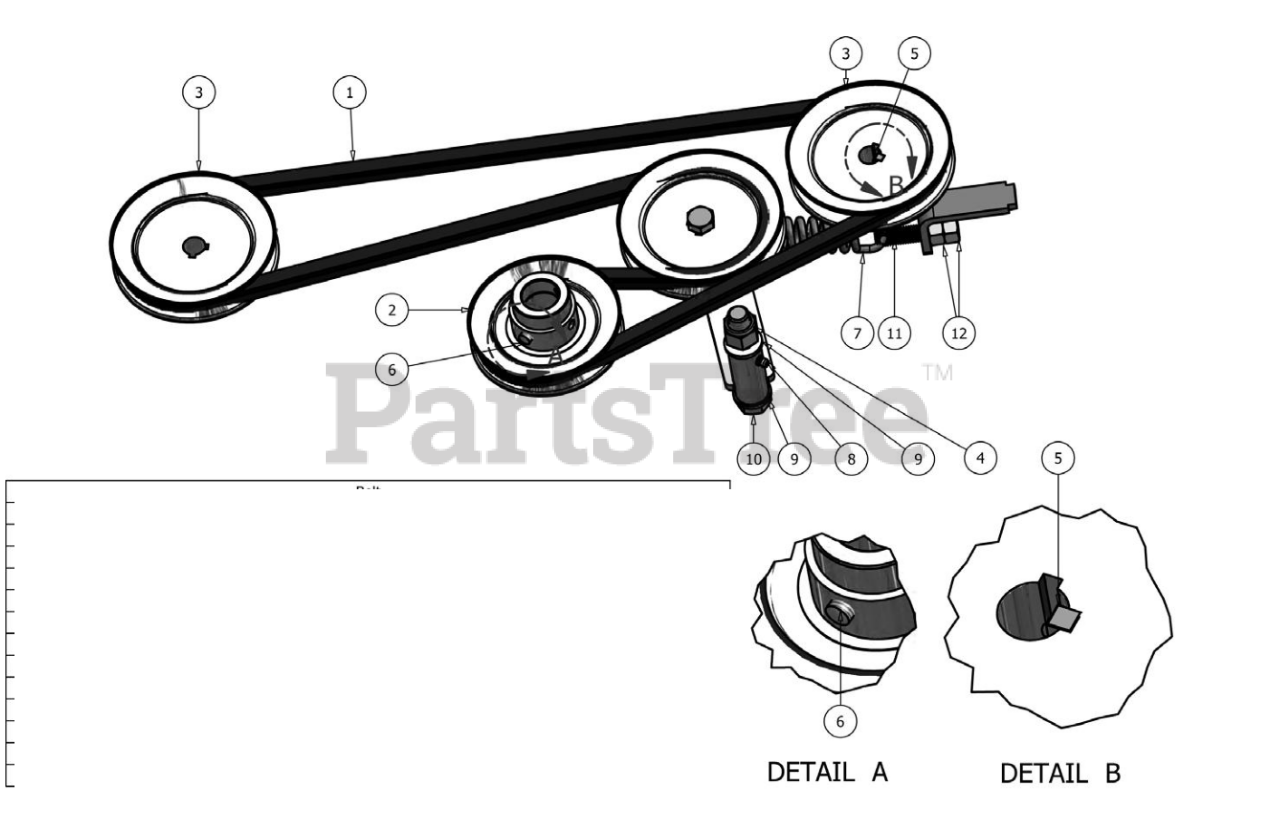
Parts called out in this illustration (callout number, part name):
2	4 3/4" Motor Pulley
3	5" Pump Pulley
4	5/8" Nylock Nut
5	5mm x 1 Key
6	3/8" Set Screw
7	Pump Idler Spring 6"
8	Grease Fitting (Drive-In Type)
9	.635 ID Plastic Washer
10	5/8" x 4" Hex Bolt
11	Spring Tensioner
12	1/2" Hex Nut
